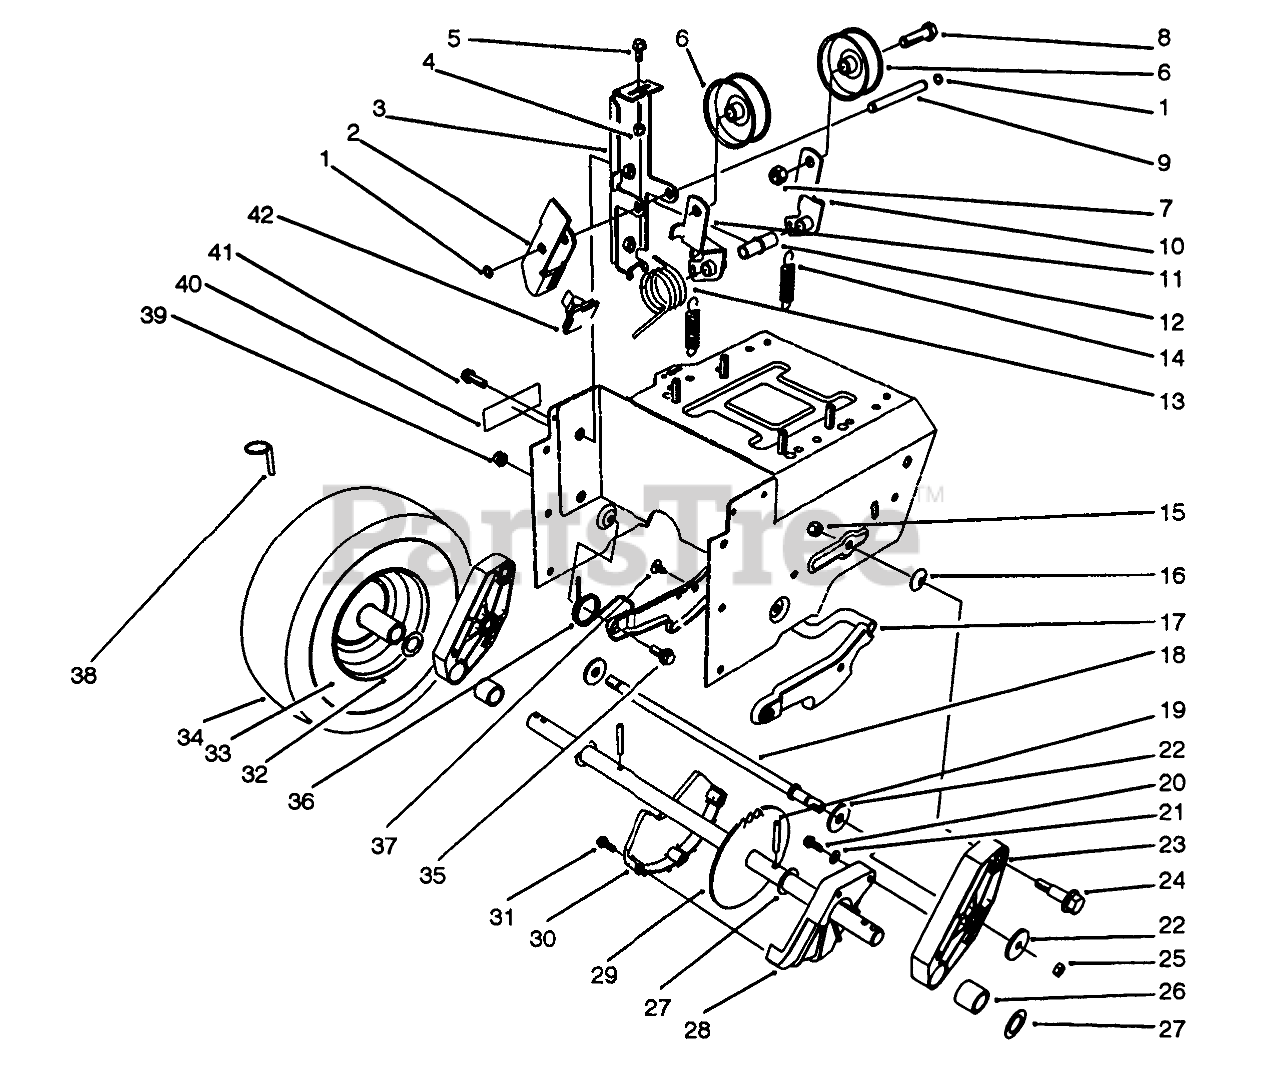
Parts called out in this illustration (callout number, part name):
1	RING-RETAINING
2	ARM-BRAKE
3	IDLER ARM BRACKET ASM
4	NUT-LOCK, NI
5	SCREW-HHF
6	PULLEY-IDLER
7	NUT-LOCK, NI
8	SCREW-HH
9	PIN-IDLER
10	ARM-IDLER, TRACTION
11	ARM-IDLER, IMPELLER
12	BUSHING-IDLER
13	SPRING-TORSION
14	SPRING-EXTENSION
15	NUT-LOCK, NI
16	WASHER-SPRING
17	Latch-Arm
18	ROD-LATCH
19	PIN-ROLL, SLOTTED
20	SCREW-HWH
21	WASHER-FLAT
22	WASHER-SUPPORT
23	Pivot Arm Assembly (Incl. Ref. #26)
24	BOLT-SHOULDER
25	NUT-LOCK, NI
26	BUSHING-AXLE
27	WASHER-THRUST
28	GUARD-CHAIN, LH
29	AXLE ASM
30	GUARD-CHAIN, RH
31	Screw
32	WHEEL
33	TUBE-INNER
35	SCREW-SHOULDER
36	SPRING-LATCH, TORSION
37	FASTENER-PANEL
38	PIN-LYNCH
39	NUT-LOCK, NI
40	DECAL-WARNING
41	SCREW-HHF
42	PAD-BRAKE
